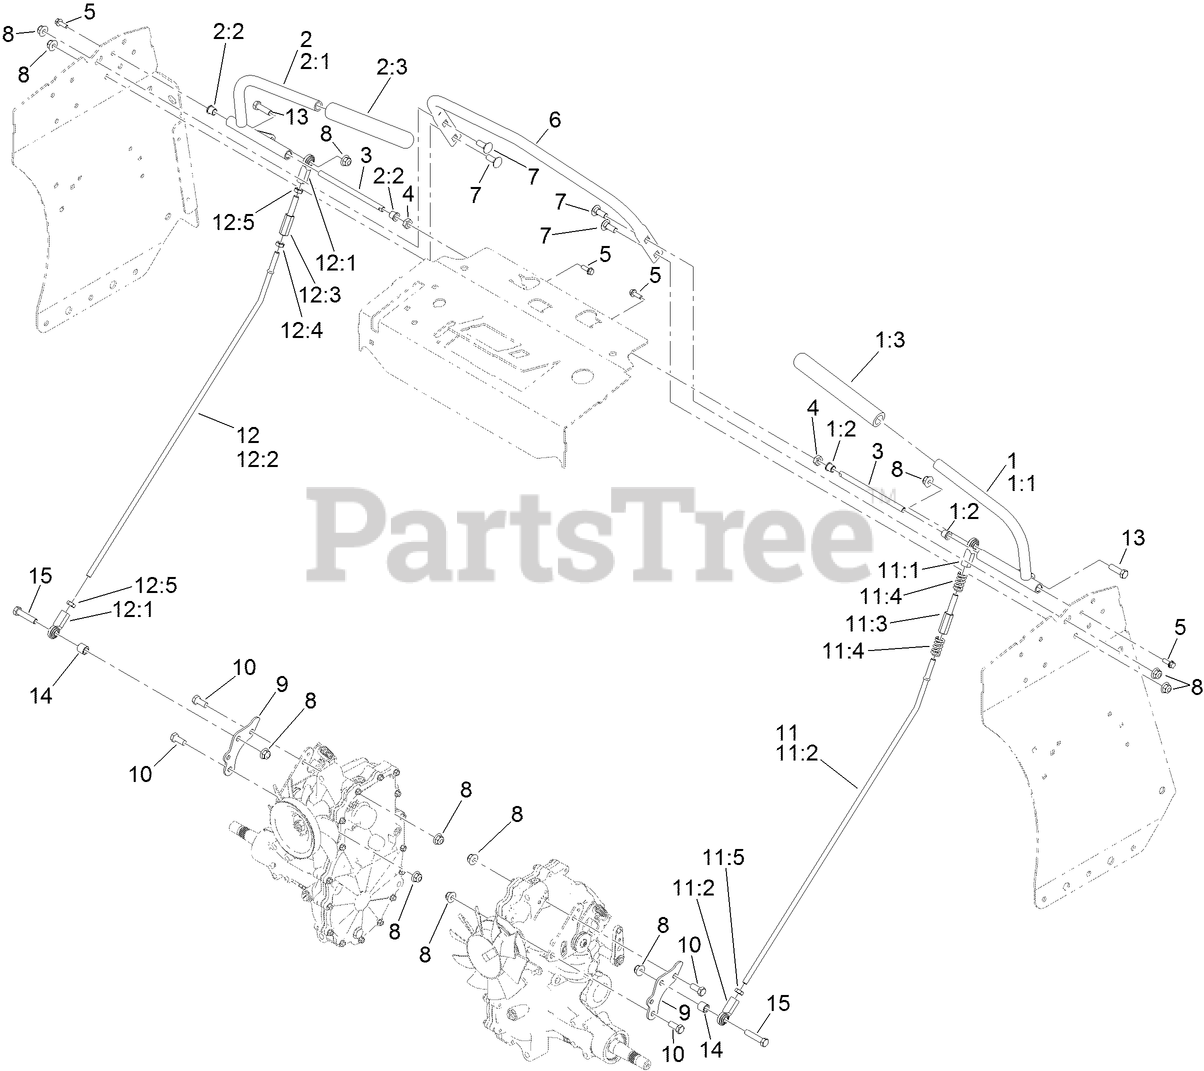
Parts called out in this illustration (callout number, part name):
1	LH MOTION HANDLE ASM
1:1	HANDLE-CONTROL, LH
1:2	BEARING
1:3	GRIP-LEVER, CONTROL
2	RH MOTION HANDLE ASM
2:1	HANDLE-CONTROL, RH
2:2	BEARING
2:3	GRIP-LEVER, CONTROL
3	SHAFT-PIVOT, MOTION CONTROL
4	SPACER-SHAFT, DRIVE LEVER
5	SCREW-HHF
6	BAR-REFERENCE
7	SCREW-HH
8	NUT-HF, NI
9	ARM-MOTION
10	SCREW-HH
11	LH MOTION LINKAGE ASM
11:1	JOINT-BALL, END
11:2	LINKAGE-MOTION
11:3	ROD-ADJUSTMENT
11:4	Spring-Compression
11:5	NUT-HJ
12	RH MOTION LINKAGE ASM
12:1	JOINT-BALL, END
12:2	LINKAGE-MOTION
12:3	ROD-ADJUSTMENT
12:4	NUT-HEX JAM, LH
12:5	NUT-HJ
13	SCREW-HH
14	SPACER
15	SCREW-HH
